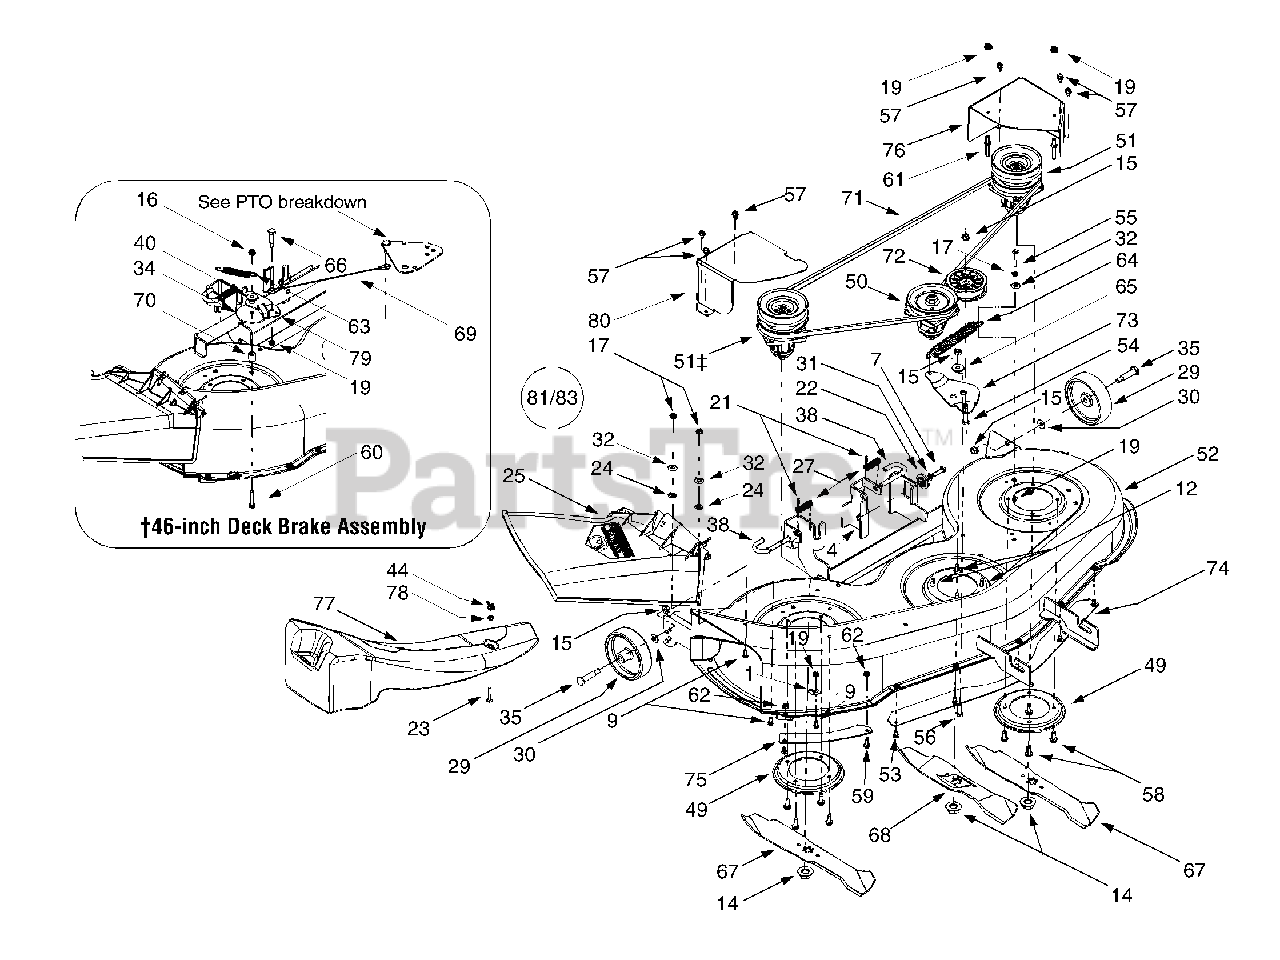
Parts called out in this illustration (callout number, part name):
1	Retainer Hook
7	Hex Cap Screw, 5/16-18 x 1.25
9	Hex Cap Screw, 1/4-20 x .62
12	Self-tapping Screw, 5/16-18 x .75
14	Hex Flange Nut, 5/8-18
15	Flange Lock Nut, 3/8-16
16	Flange Lock Nut, 5/16-18
17	Hex Nut, 1/4-20
19	Hex Flange Lock Nut, 1/4-20
21	Cotter Pin, 3/32 x 1.0
22	Deck Adjustment Gear
23	Screw, 1/4-20 x 1.5
24	Push Nut. .25 x .5
25	Side Discharge Chute Assembly
27	Compression Spring, .406 x .531 x 1.75
29	Deck Wheel, 5 x 1.38
30	Bell Washer, .401 x .87 x .063
31	Lock Washer, 5/16
32	Bell Washer, .265 x .75 x .062
34	Flat Washer, .320 x 3.0 x .125
35	Shoulder Screw, .498 x 1.53
38	Deck Release Pin
40	Shoulder Spacer
44	Wing Nut, 1/4-20
51	Double Pulley Spindle Assembly
54	Hex Cap Screw, 3/8-16 x 1.75
55	Hex Cap Screw, 1/4-20 x 2.0
56	Hex Cap Screw, 3/8-16 x 1.0
57	Self-tapping Screw,1/4-20 x .5
58	Self-tapping Screw,15/16-18 x .875
59	Hex Screw, 1/4-20 x .75
60	Hex Cap Screw, 5/16-18 x 1.5
61	Belt Keeper Pin
62	Hex Sems Nut, 1/4-20
63	Extension Spring, .5 x 3.97
64	Extension Spring, .91 x 7.33
65	Shoulder Spacer, .625 x 1.16
66	Shoulder Screw, .374 x 1.16
67	Three-in-one Blade, Star Center, 16.28"
68	Three-in-one Blade, Star Center, 14.88"
69	Bracket Cable, 12"
70	Spacer, .385 x .625 x .70
71	Deck Belt
72	Flat Idler Pulley, 3.5 OD
77	Mulch Plug, 46-inch Decks
78	Hex Lock Nut, 1/4-20
79	Deck Brake Assembly, 46-inch Decks
